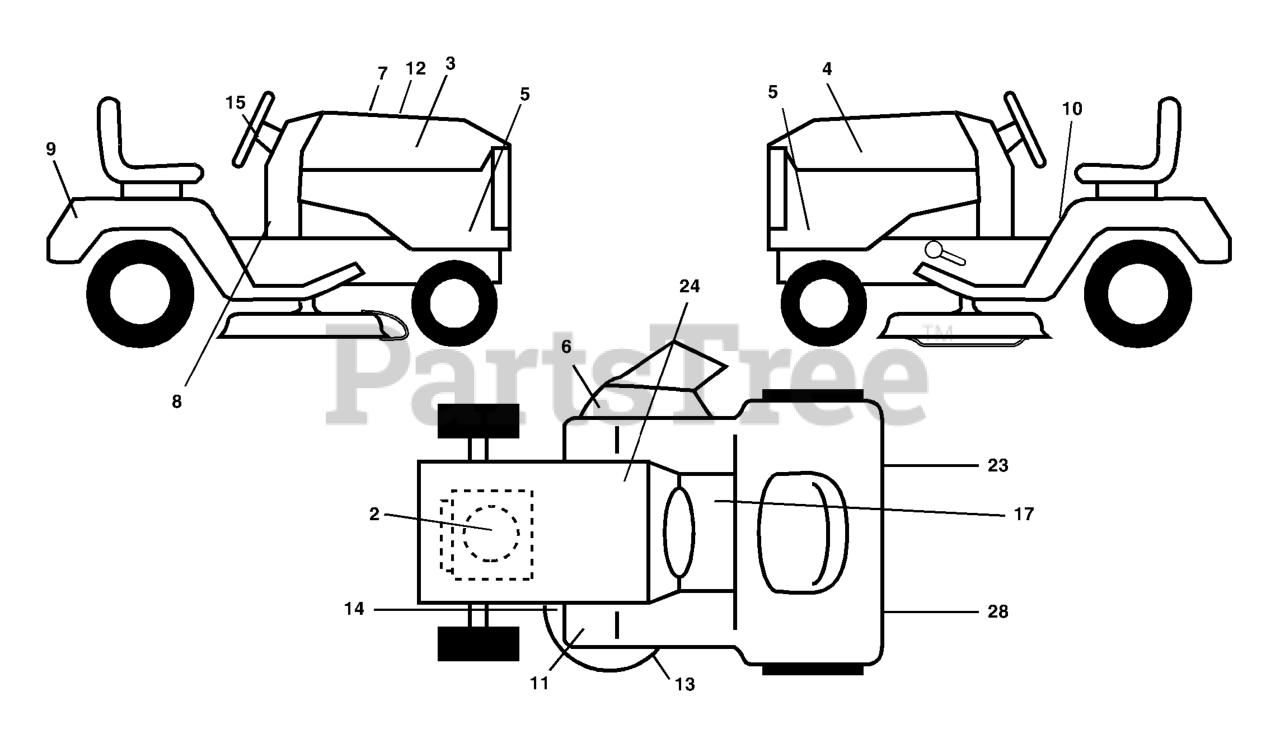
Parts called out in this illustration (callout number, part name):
2	DECAL.ENG.25HP.KAWA.HSQV.XP
3	RH HOOD DECAL
4	LH HOOD DECAL
5	DECAL HOOD SIDES
6	DECAL.WARN.KEEP.HAND.AWAY
7	AUGER HOUSING
8	DECAL, DASH
9	DECAL, FENDER
10	DECAL FENDER DANGER
11	DECAL, FOOTREST
12	DECAL, FINAL
13	DECAL V-BELT SCHEMATIC
14	DECAL CLUTCH/BRAKE
15	DECAL.WHEEL.STEERING.HUSQ.PERM
17	DECAL PARK BRAKE
23	REFLECTOR, RH
24	DECAL BTRY SYMBOLS
27	DECAL.BYPASS.FENDER.CRD.LT.YT
28	REFLECTOR, LH
